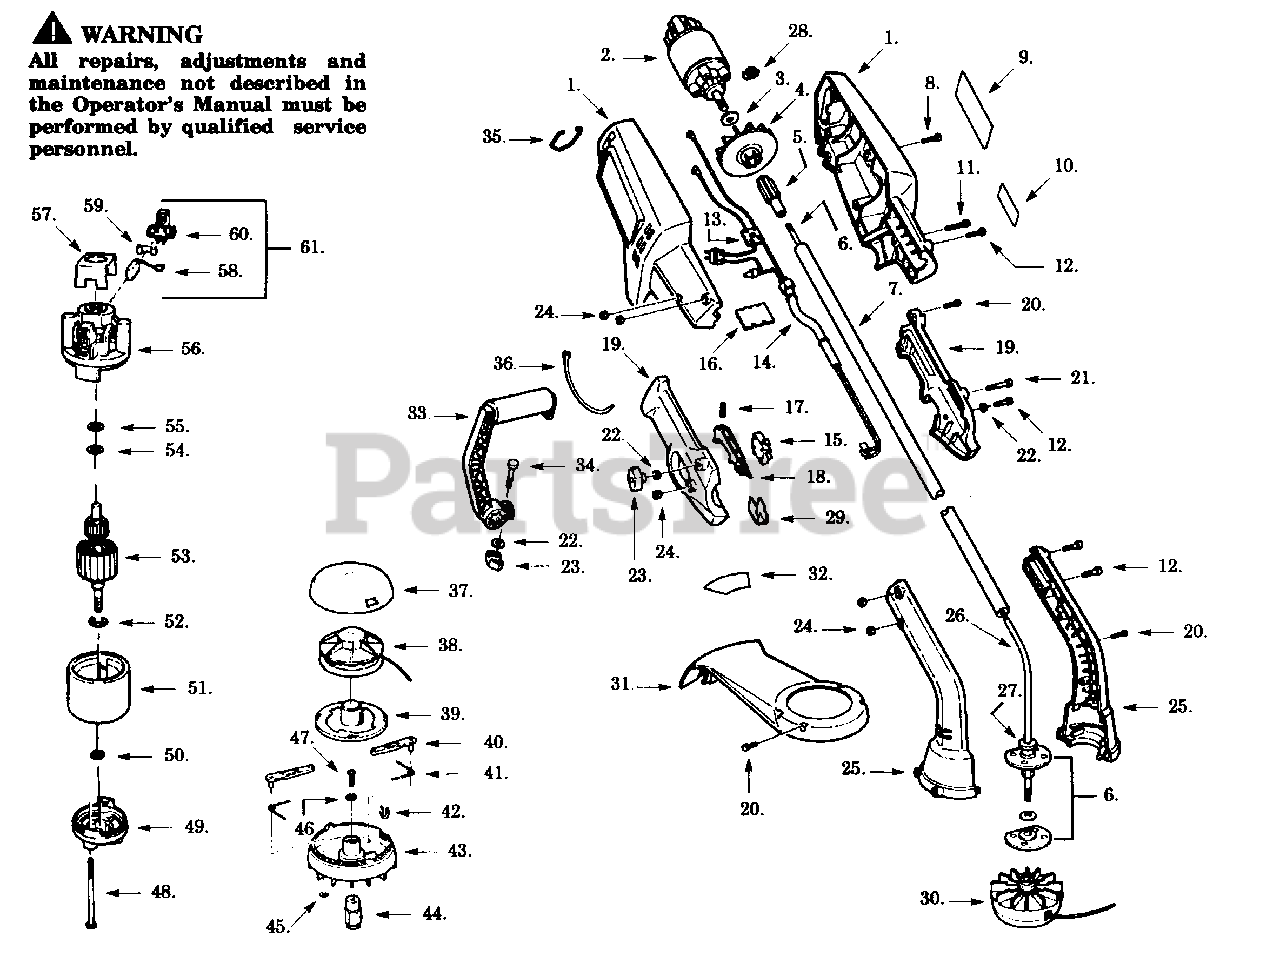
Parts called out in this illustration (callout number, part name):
1	Motor Hsg. Set
2	Motor Ass'y.
5	Shaft Adapter
6	Flex Shaft/Bearing Ass'y. Kit
7	Tube Ass'y.
9	Warning Label
10	Motor Hsg. Label (Not a serviceable part)
13	P.C. Bridge
14	Harness Ass'y.
16	Wire Mount Board
17	Trigger Spring
19	Trigger Hsg. Set
25	Spindle Hsg. Set
26	Tubing Sleeve
27	Felt Washer
28	Retaining Ring
29	Switch Insulator
30	Cutting Head Ass'y.
31	Guard Ass'y.
32	Guard Label (Not a serviceable part)
33	Assist Handle
36	Tie Strap
38	Spool w/Line
42	Line Shield
43	Housing Head
44	Drive Adaptor
45	Push Nut
49	Endbell Ass'y. (Drive)
51	Field Ass'y.
52	Retaining Ring
53	Armature Ass'y.
56	Endbell Ass'y. (Brush)
57	Insulator
59	Spring Brush
60	Brush Holder
61	Brush Holder Ass'y.
